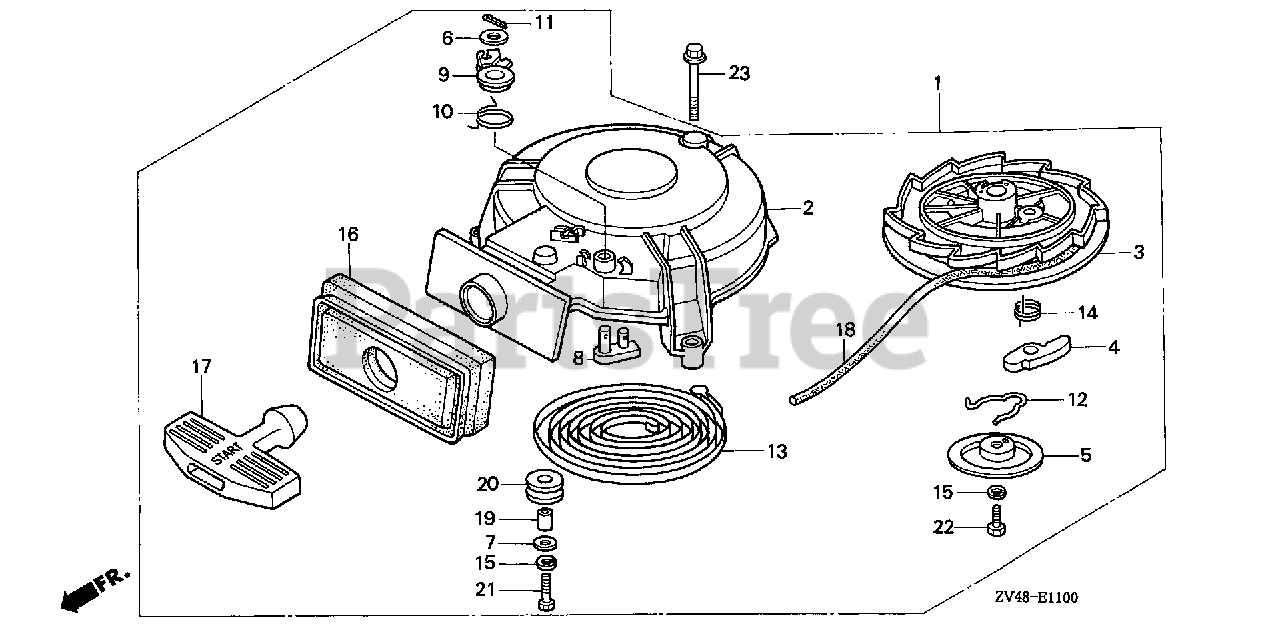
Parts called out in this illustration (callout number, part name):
1	STARTER ASSY., RECOIL
2	CASE, RECOIL STARTER
3	REEL, RECOIL STARTER
4	RATCHET, STARTER
5	PLATE, FRICTION
7	WASHER, THRUST
8	STOPPER, REEL
9	ARM, STOPPER
10	SPRING, STOPPER
11	PIN, SPLIT
12	SPRING, FRICTION
13	SPRING, RECOIL STARTER
14	SPRING, RETURN
15	WASHER, SPRING
16	SEAL, RECOIL
17	GRIP, STARTER
18	ROPE, RECOIL STARTER (N/A: USE P/N 08550-ZG921-11)
19	GUIDE, ROLLER
20	ROLLER, STARTER
21	BOLT, HEX. (6X25)
22	BOLT, HEX. (6X14)
23	BOLT, FLANGE (6X30)
